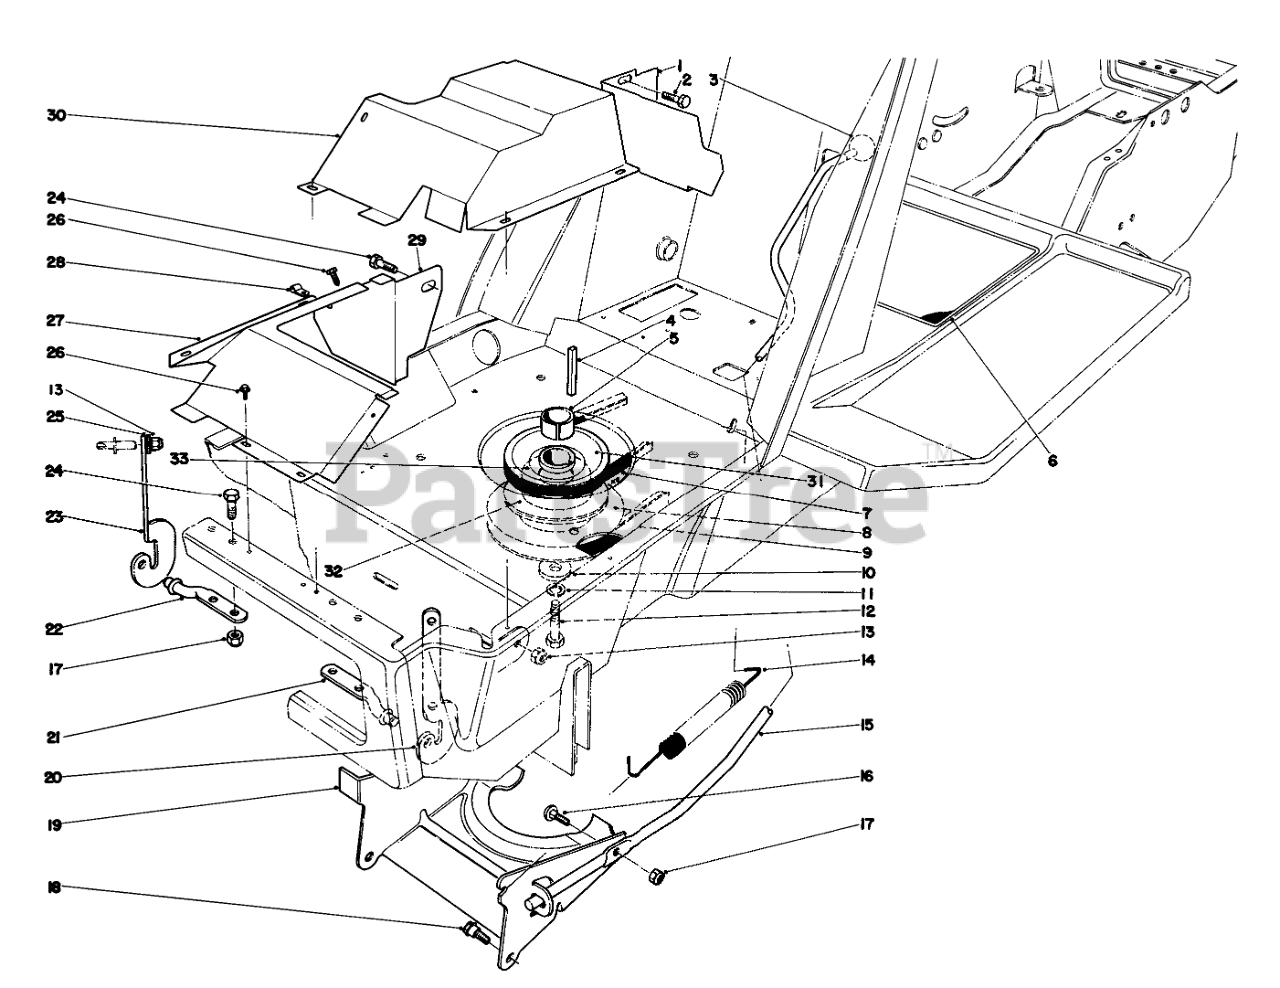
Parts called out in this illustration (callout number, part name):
1	EXH SHIELD SUPT B
2	SCREW-HH
4	KEY-SQUARE
5	PULLEY SPACER
6	OPERATION DECAL
7	V BELT
8	CLUTCH KIT W/O
9	V-BELT, ENG/DECK
10	WASHER
11	WASHER-LOCK
12	SCREW-HH
13	NUT-LOCK, CONE
14	TRACTION SPRING
15	Engagement Lever
16	Bolt
17	NUT-LOCK, CONE
18	SCREW-SHOULDER
19	CLUTCH ACTUATOR R
20	L.H. HINGE BRACKET
21	LH HOOD HINGE PIN
22	RH HOOD HINGE PIN
23	RH HINGE BRKT
24	SCREW-HH
25	SCREEN SUPT BRKT
26	SCREW-HWHTF
27	Heat Shield
28	CABLE CLAMP
29	Support Heat Shield
30	HEAT SHIELD WA B
31	Sheave
32	CLUTCH PLATTER
33	SPRING WASHER
